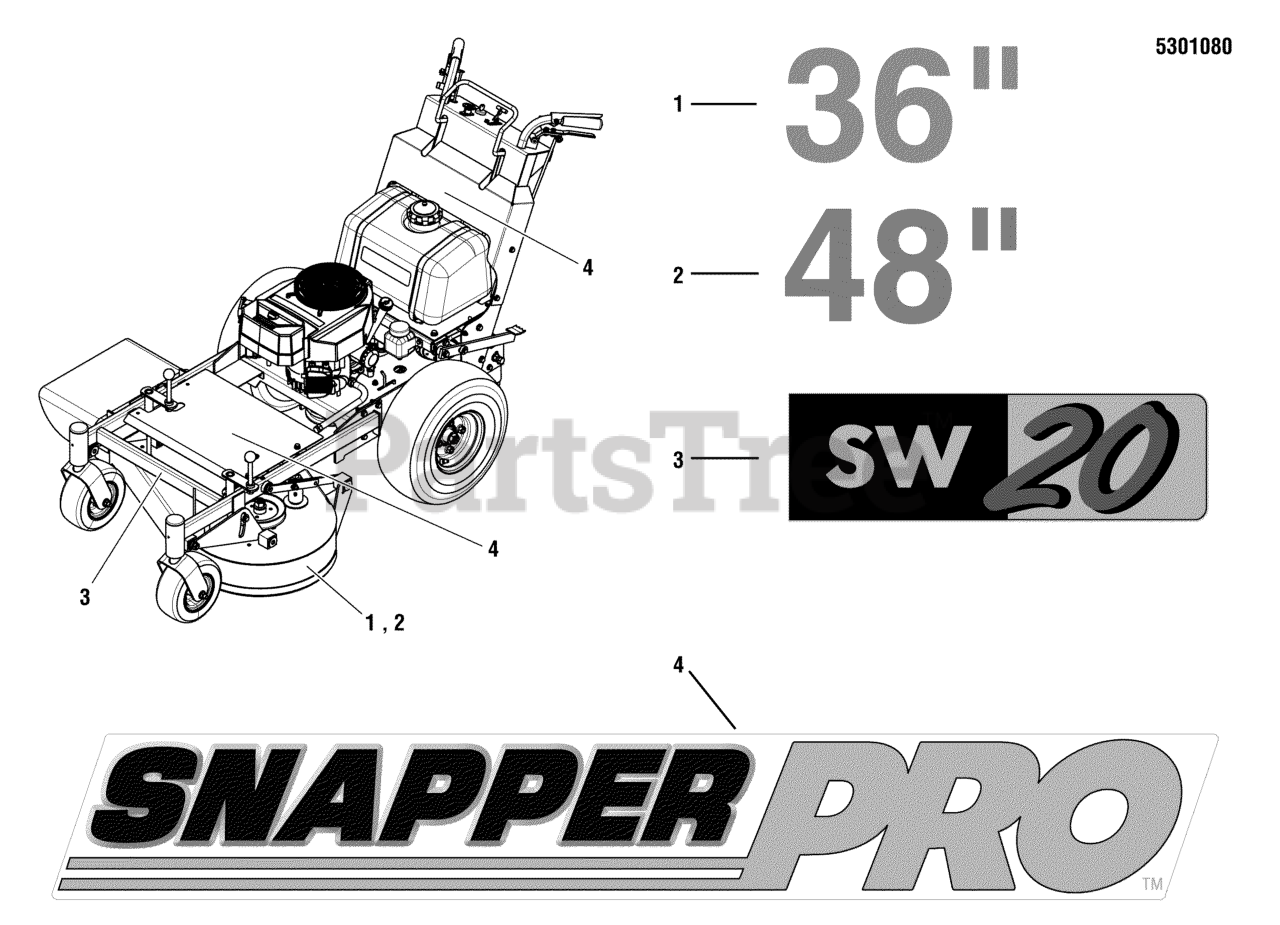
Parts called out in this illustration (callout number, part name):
1	DECAL, 36"
2	DECAL, 48
3	DECAL, SW20
4	DECAL, SNAPPER PRO
